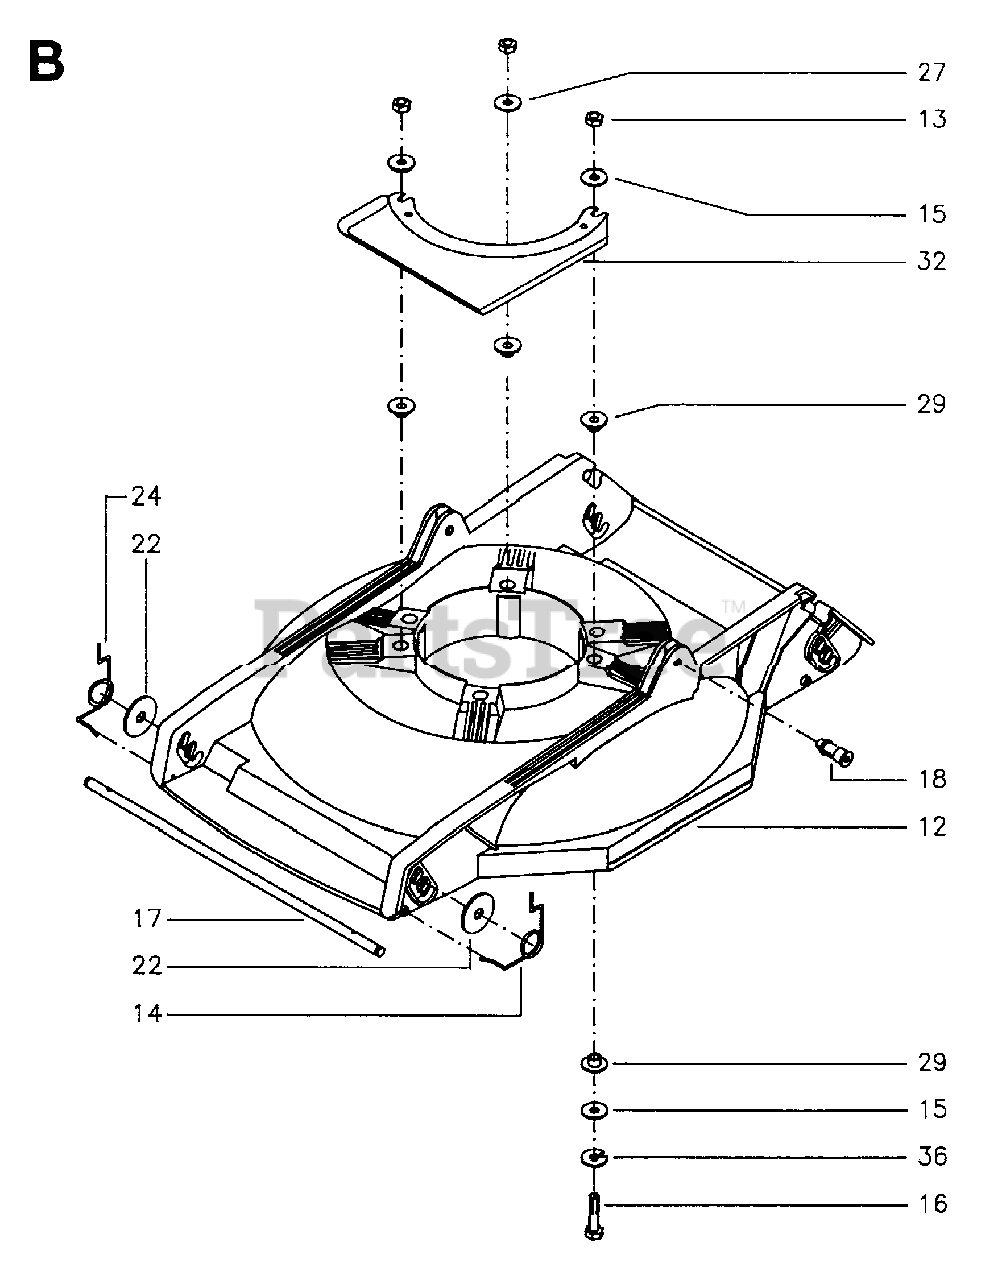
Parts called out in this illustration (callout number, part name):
13	LOCKNUT M8
15	WASHER BRB 8.4X17
29	FLANGE BRG.
32	PROTECTOR
36	SPRING WASHER
